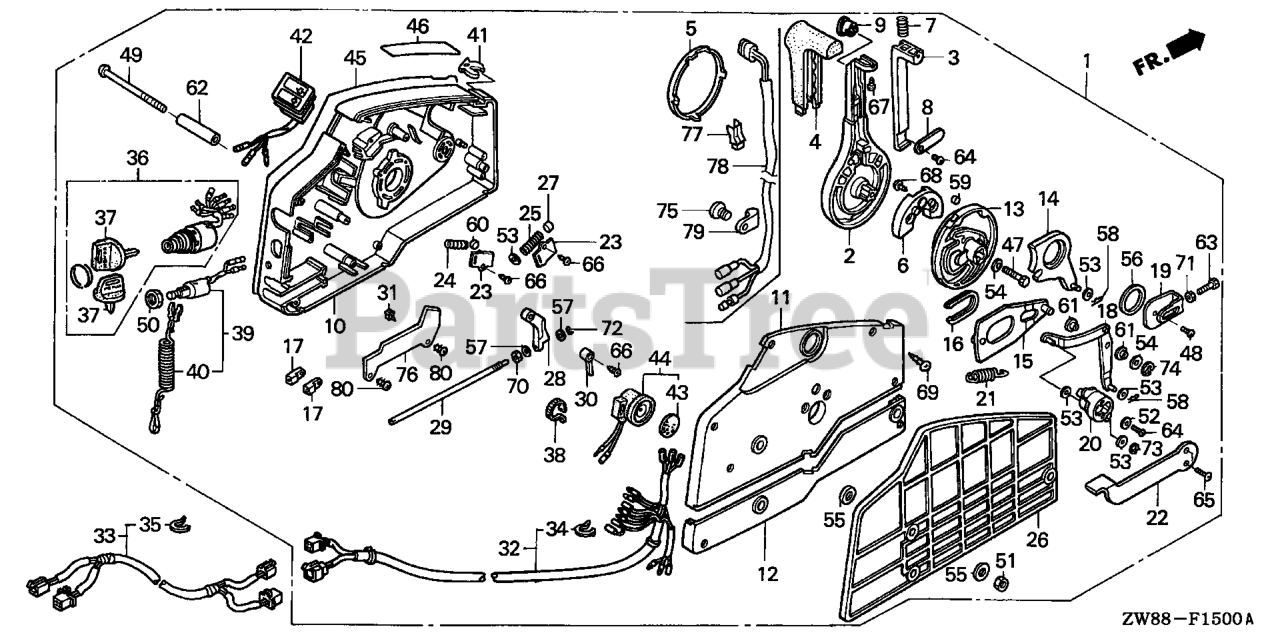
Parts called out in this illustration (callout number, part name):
1	S/R SW 2 LIGH POW TL
2	HANDLE, REMOTE CONTROL
3	LEVER, HANDLE LOCK
4	GRIP, REMOTE CONTROL HANDLE
5	CAP, HANDLE
6	BLOCK, NEUTRAL LOCK
7	SPRING, REMOTE CONTROL HANDLE
8	PLATE, LEVER SETTING
10	HOUSING, REMOTE CONTROL BOX (A)
11	HOUSING, REMOTE CONTROL BOX (B)
12	HOUSING, REMOTE CONTROL BOX (C )
13	WHEEL, CONTROL
14	ARM, SHIFT LINK
15	PLATE, SLIDING
16	COLLAR, SLIDING PLATE
17	PIVOT, SHIFT
18	ARM, LINK JOINT
19	BRACKET, LINK JOINT
20	WHEEL, ACCELERATOR
21	SPRING, ACCELERATOR WHEEL
22	LEVER, IDLE
23	PLATE, SPRING SETTING
24	SPRING, SHIFT CLICK
25	SPRING, CHOKE RETURN
26	SPACER, REMOTE CONTROL BOX
27	SPACER, CLICK SPRING
28	BLOCK, THROTTLE FRICTION
29	BOLT, FRICTION
30	SPACER, NEUTRAL SWITCH
31	SPACER, CABLE CLAMP
32	CABLE ASSY. B, REMOTE CONTROL (4P+6P)
33	CABLE ASSY., REMOTE CONTROL EXTENSION (4P+4P)
33	CABLE ASSY., REMOTE CONTROL EXTENSION (4P+6P)
34	TIE, CABLE (NATURAL 2.4X92) Use up to Frame SN 1300359.
35	TIE, CABLE (NATURAL 2.4X92) Use up to Frame SN 1300359.
36	SWITCH ASSY., COMBINATION DUAL QTY = (2) (SINGLE)
37	KEY ASSY., COMBINATION SWITCH (35100-ZV5-003 ONLY) DUAL QTY = (4) (SINGLE)
38	BAND (BLACK 3.5X140)
39	SWITCH ASSY., EMERGENCY STOP
40	WIRE, EMERGENCY DUAL QTY = (2) (SINGLE)
41	CLIP, EMERGENCY LOCK
42	LAMP ASSY., INDICATOR
43	PLATE, TURN SIGNAL BUZZER DUAL QTY = (2) (SINGLE)
44	BUZZER, WARNING DUAL QTY = (2) (SINGLE)
45	PLATE, REMOTE CONTROL (CAUTION=SILVER)
46	MARK, FAST IDLE
47	BOLT, HEX. (8X35) Use up to Frame SN 4800712.
48	SCREW, PAN (6X10)
49	SCREW (6X95)
50	NUT, HEX. (16MM) DUAL QTY = (2) (SINGLE)
51	NUT, HEX. (6MM)
52	WASHER, PLAIN (5MM)
53	WASHER, PLAIN (6MM) Use up to Frame SN 4800342.
54	WASHER, PLAIN (8MM) Use up to Frame SN 4800712.
55	WASHER (6MM)
56	WASHER (28MM)
57	WASHER, PLAIN (4MM) Use up to Frame SN 4800712.
58	PIN, LOCK (6MM)
60	ROLLER, CLICK
61	COLLAR, LINK JOINT
62	COLLAR, DISTANCE (6X10X43.5)
63	BOLT, HEX. (5X16)
64	SCREW, PAN (5X10)
65	SCREW, OVAL (5X12) Use up to Frame SN 4800712.
66	SCREW, TAPPING (5X10)
67	SCREW, TAPPING (5X12)
68	SCREW, TAPPING (6X16)
69	SCREW, TAPPING (5X25)
70	NUT, HEX. (6MM)
71	NUT, HEX. (5MM)
72	E-RING (3MM)
73	E-RING (4MM)
74	E-RING (7MM)
75	CLAMP, HARNESS
76	CLAMP, POWER TILT CORD
77	PIPE, HARNESS GUIDE
78	SWITCH ASSY., POWER TRIM-TILT
79	CLIP, WIRE HARNESS (6.3MM)
80	SCREW, TAPPING (5X8) (FOR SILVER MUFFLER)
